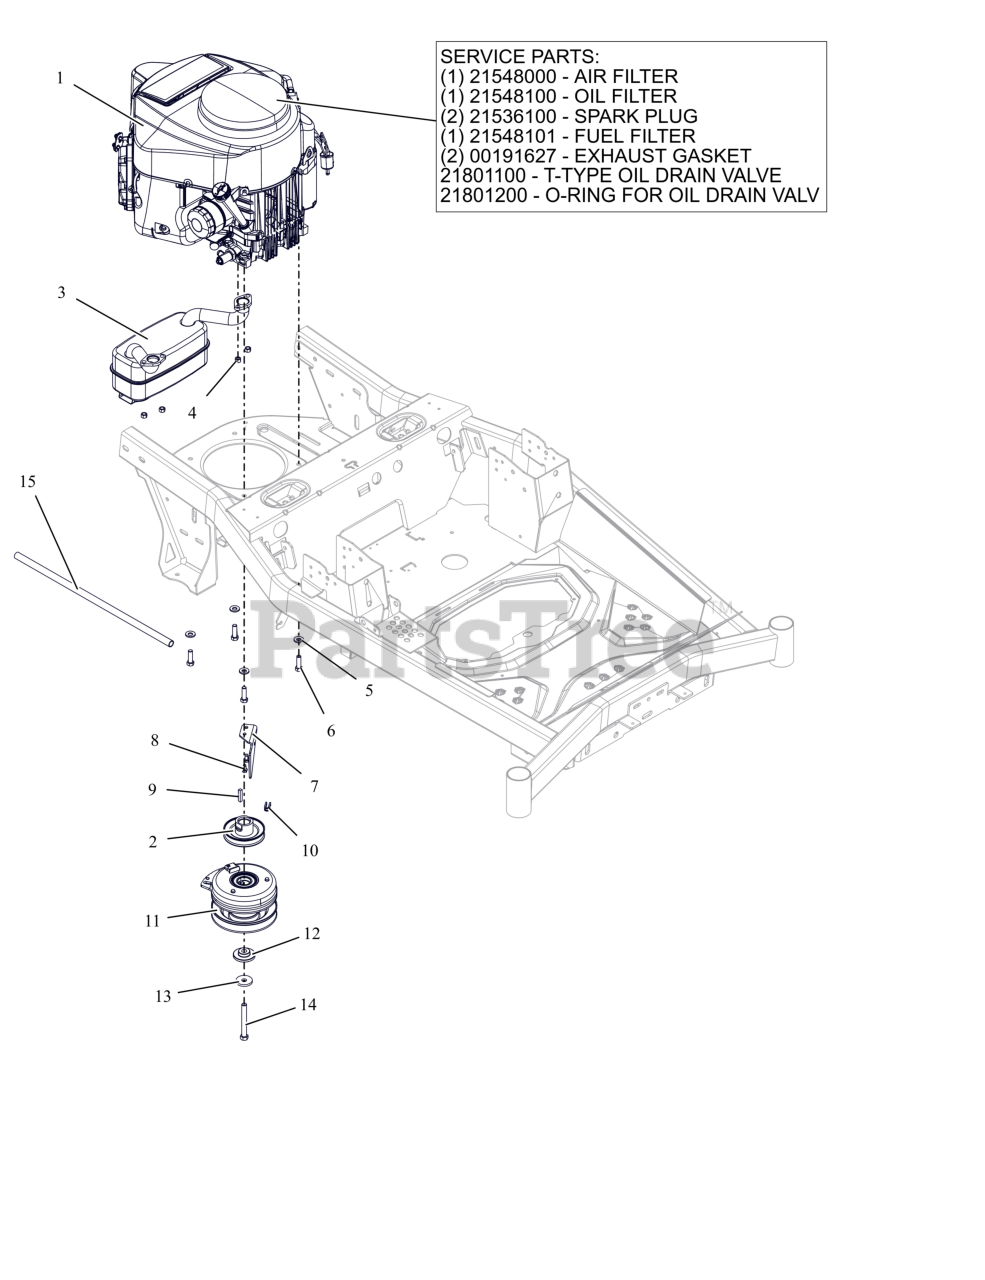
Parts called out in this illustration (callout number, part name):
1	ENGINE, KAWASAKI FR730 24HP
1	AIR FILTER, KAWASAKI FR
1	OIL FILTER, KAWASAKI FR
1	PLUG, SPARK
1	FUEL FILTER-KAWASAKI FR
1	GASKET, MUFFLER S/O
1	VALVE- T-TYPE OIL DRAIN
1	O-RING- OIL DRAIN VALVE
2	WLDMT-PULLEY-4.831OD X1.003
3	MUFFLER - KAWASAKI
4	NUT-LK-TOP-FLG M8 ZCC
5	WASHER, 3/8" SPRING DISC
6	BLT, HEX .38-16X1.25 G5 ZCC NT
7	BRKT- CLUTCH STOP
8	SCR-TAP .25-20X.50 HWH ZCC
9	KEY-SQ .25 X 1.25 X .25 SAE
10	BSHG, CLUTCH
11	CLUTCH, WARNER-IXR-18211
12	BSHG-FLG .469X1.06X.574X2.0
13	WASHER, 7/16" SPRING DISK
14	BLT- HEX .44-20X3.50 G8 ZCC NT
15	HOSE- OIL DRAIN
